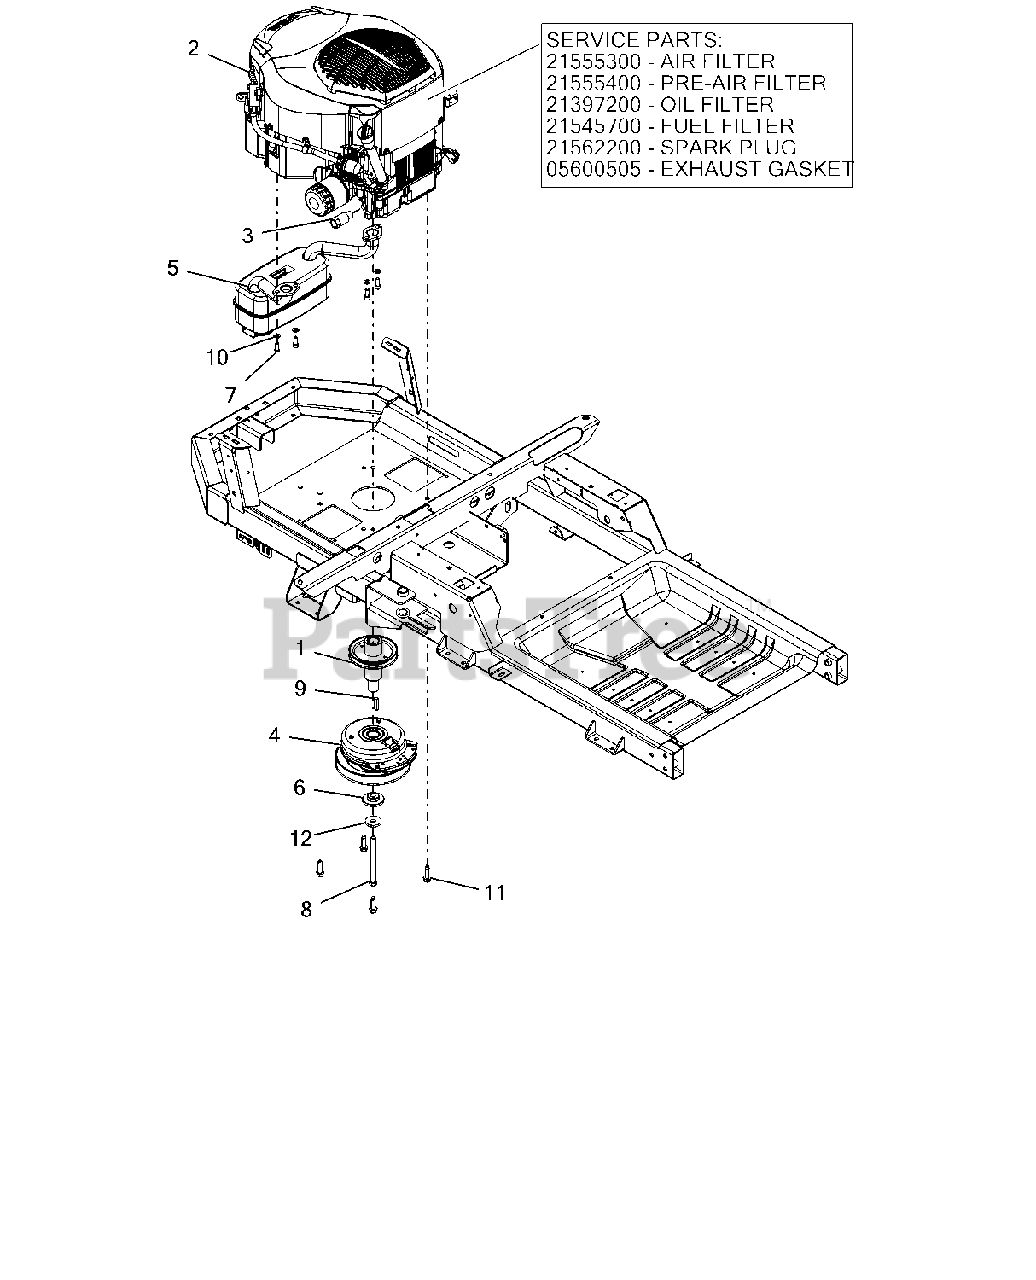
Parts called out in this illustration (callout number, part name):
1	WLDMT, DRIVE SHEAVE (LONG)
2	ENGINE, KOHLER TWIN 26 PRO W/SC
2	AIR FILTER
2	PRE-AIR FILTER
2	OIL FILTER
2	FUEL FILTER
2	SPARK PLUG
2	EXHAUST GASKET
3	DRAIN, OIL
4	CLUTCH, ELEC 105 FT LB MONOPOLE 6.83"
5	MUFFLER, KOHLER
6	BSHG, -FLG .469 x 1.06 x .574 x 2.0
7	SCR, CAP SOCKET HEAD
8	BLT-HEX .44-20X5.00 GR8 YWZC NYTORQ
9	KEY-SQ .250X.250X1.250
10	WSHR-LK .31X.078 REG YWZC
11	SCR-TAP .38-16X1.25 HWH TR YZ
12	WSHR, 7/16" SPRING DISC
